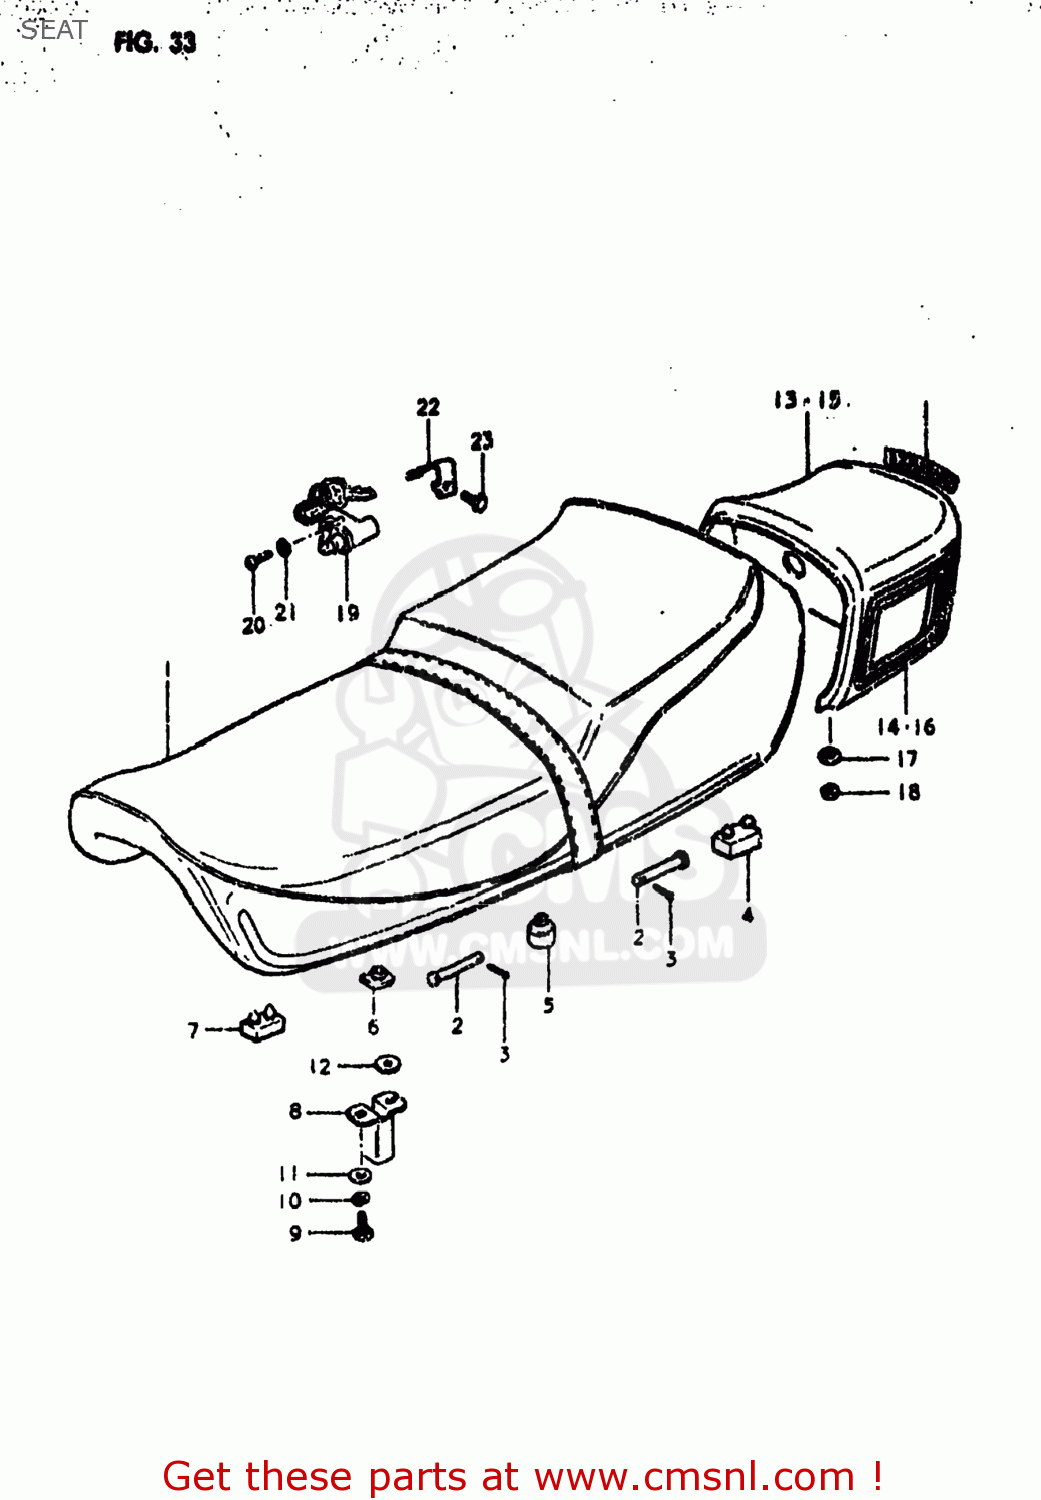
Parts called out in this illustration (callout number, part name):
1	SEAT ASSEMBLY
2	PIN
3	PIN
4	CUSHION
5	CUSHION(11.5X22X20)
6	CUSHION
7	CUSHION
8	STRIKER,SEAT LOCK
9	BOLT
10	LOCK WASHER
11	WASHER 6MM
12	WASHER(8.5X18X1)
13	COVER,SEAT TAIL
14	TAPE SET,SEAT TAIL COVER
15	COVER,SEAT TAIL
16	TAPE SET,SEAT TAIL COVER
17	WASHER
18	NUT 6MM
19	LOCK ASSY,SEAT
20	SCREW
21	LOCK WASHER
22	SPRING,HELMET HOLDER
23	BOLT 5X16
